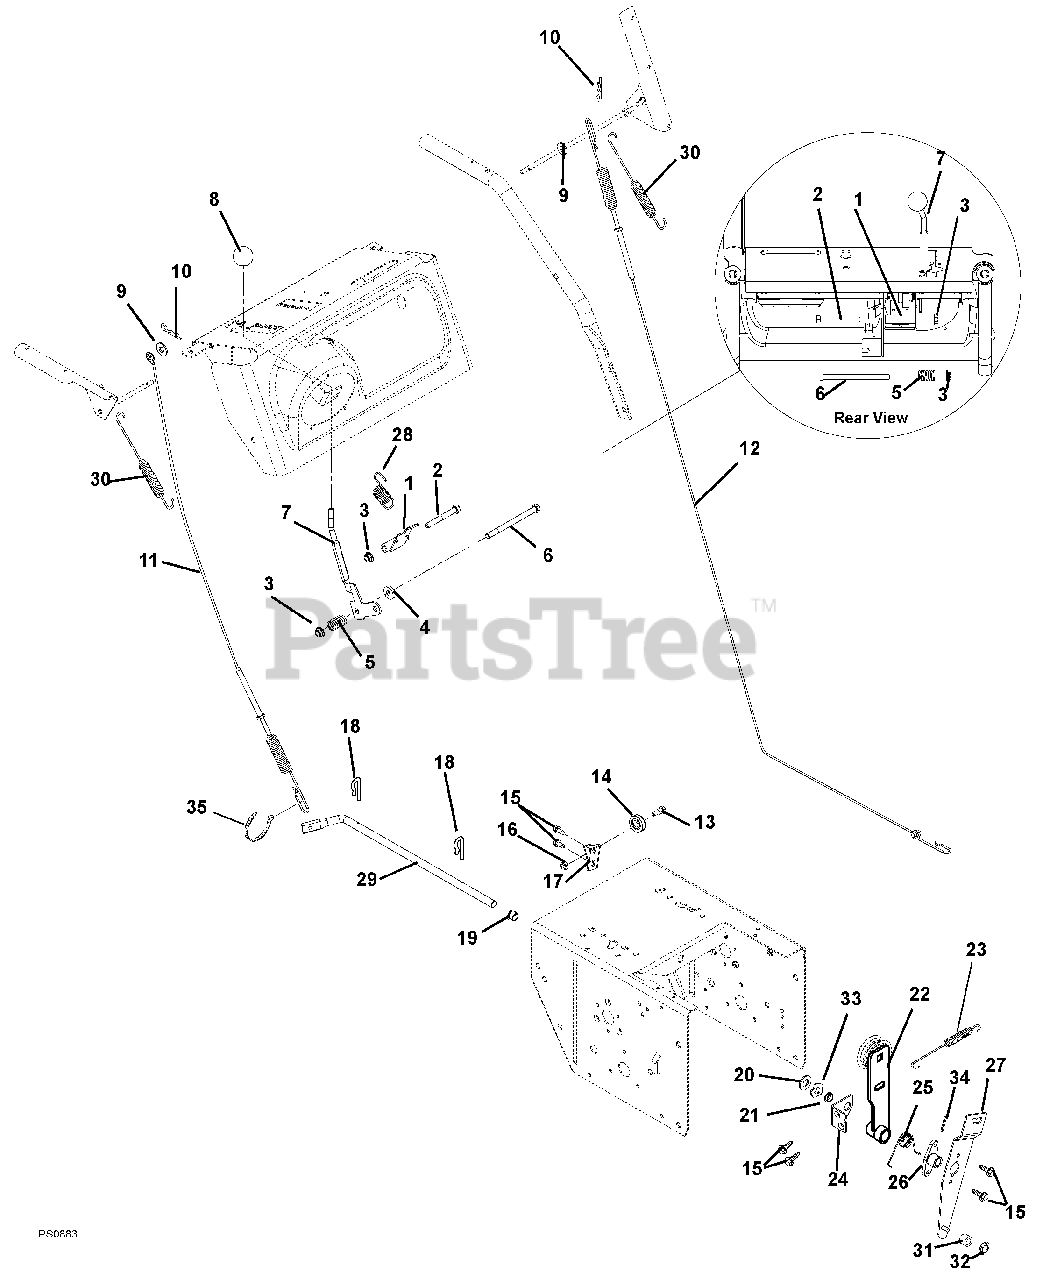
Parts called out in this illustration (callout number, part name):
1	Arm, Interlock
2	Bolt, Hex .38-16 x 3.00 Grade 5
3	Nut, Locking Top Flange .38-16
4	Washer, Flat Steel .406 x 1.00 x .188
5	Spring, Compression
6	Bolt, Hex .38-16 x 5.00 Grade 5
7	Lever, Shift
8	Knob, Ball Black
9	Washer, Flat Steel .28 x .62 x .065
10	Pin, Hair Internal .06 x .18 x .77
11	Cable, Attachment
12	Cable, Traction
13	Bolt, Shoulder .375 x .375 x .25-20
14	Pulley, Cable
15	Screw, Tap .25-20 x .50
16	Nut, Locking Top Flange .25-20
17	Bracket, Cable Pulley
18	Clip, Spring
19	Bushing, Polyliner .50 Split
20	Washer, Flat Steel .531 x 1.06 x .095
21	Bushing, Polyliner .50 Snap-in
22	Arm, Idler Traction
23	Spring, Tension
24	Bracket, Support
25	Spring, Torsion
26	Hub, Brake Arm
27	Arm, Idler Attachment
28	Spring, Tension
29	Arm, Attachment
30	Spring, Tension
31	Bushing,Sleeve
32	Ring, Retaining External .250 x .010
33	Wave Washer
34	Pin, Roll .125 x 1.00
35	Cable Tie
